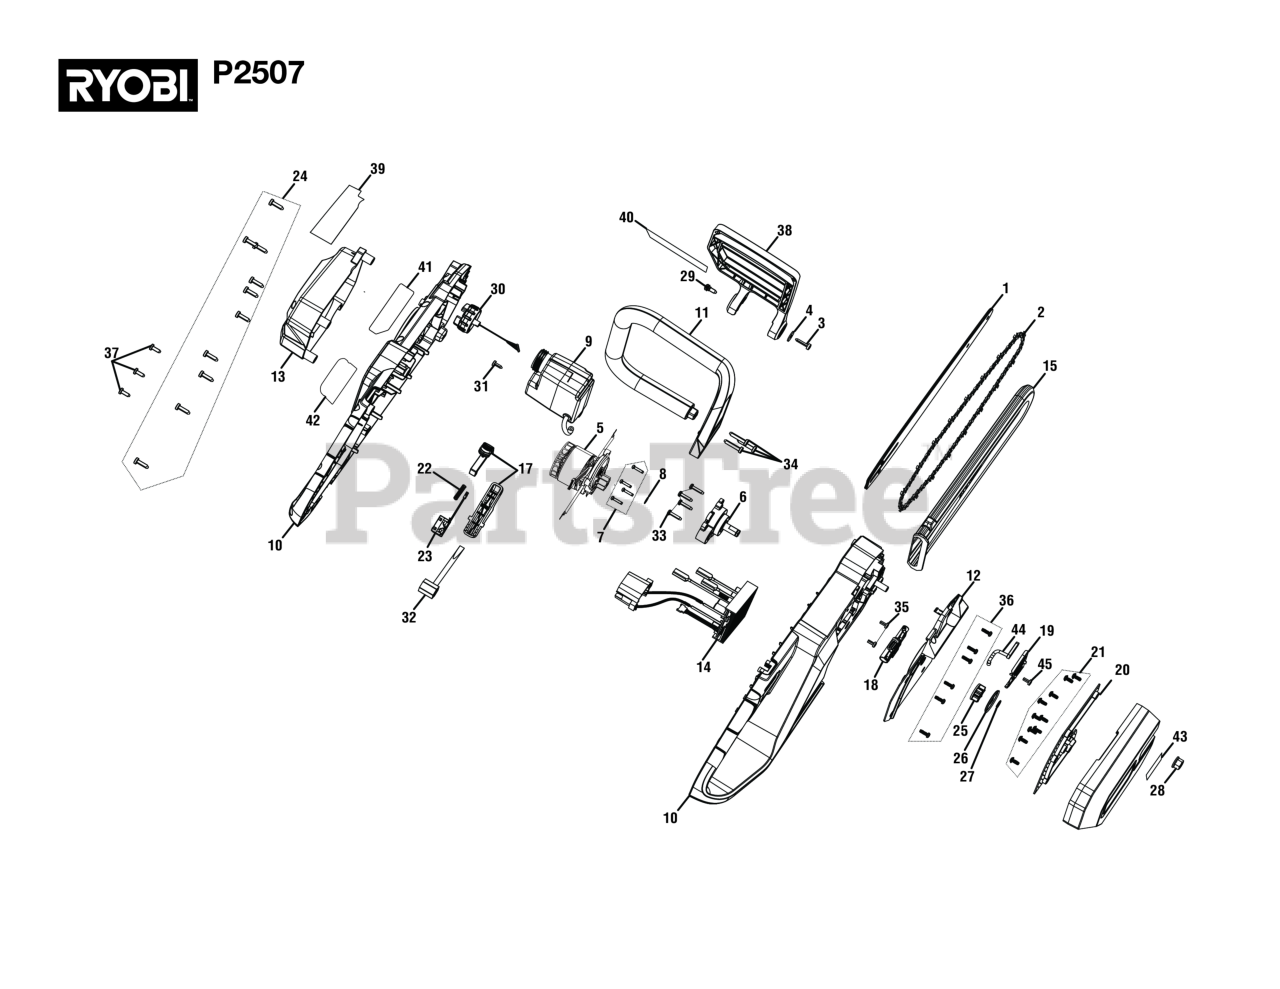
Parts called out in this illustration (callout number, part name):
1	12 in. Bar
2	12 in. Chain
3	Screw (M4 x 21 mm, T20 Torx Hd.)
4	Washer (ID5.2 x OD16 x 1.5t)
5	Motor Assembly
6	Gear Box, Output Gear and Shaft Assembly
7	Screw (M3 x 15 mm, Pan Hd.)
8	Washer (M6, ID6.2 x 11OD x 0.3t)
9	Oil Tank and Input Tube Assembly
10	Housing Assembly
11	Front Handle
12	Brake Band Cover
13	Motor Cover Assembly
14	Motor Controller and Battery Holder Assembly
16	Sprocket Cover Assembly
17	Trigger Assembly
18	Oil Pump Assembly
19	Guard Bar Plate
20	Sprocket Cover Board
21	Screw (M4 x 10 mm, T20 Torx Pan Hd.)
22	Compression Spring (Trigger Lock)
24	Screw (#10-14 x 18 mm, T25 Torx Hd.)
26	Washer (Special)
28	Hex Nut (5/16-18 Flange)
29	Screw (M5 x 15 mm, T25 Torx Hd.)
30	Oil Tank Cap Assembly
31	Screw (M4.2 x 12 mm, T20 Torx Pan Hd.)
33	Screw (M4 x 18 mm, T20 Torx Pan Hd.)
34	Screw (M5 x 25 mm, T25 Torx Pan Hd.)
35	Screw (M4 x 9.5 mm)
36	Screw, T20, M4-18X12, Low Carbon Steel,
37	Screw (#10-14 x .506 mm, T25 Torx Pan Hd.)
38	Front Guard Assembly
39	Danger Warning Label
40	Icon Warning Label
42	Data Label
43	Whisper Label
44	Output Oil Tube
45	Screw (M4 x 12 mm, T20 Torx Hd.)
